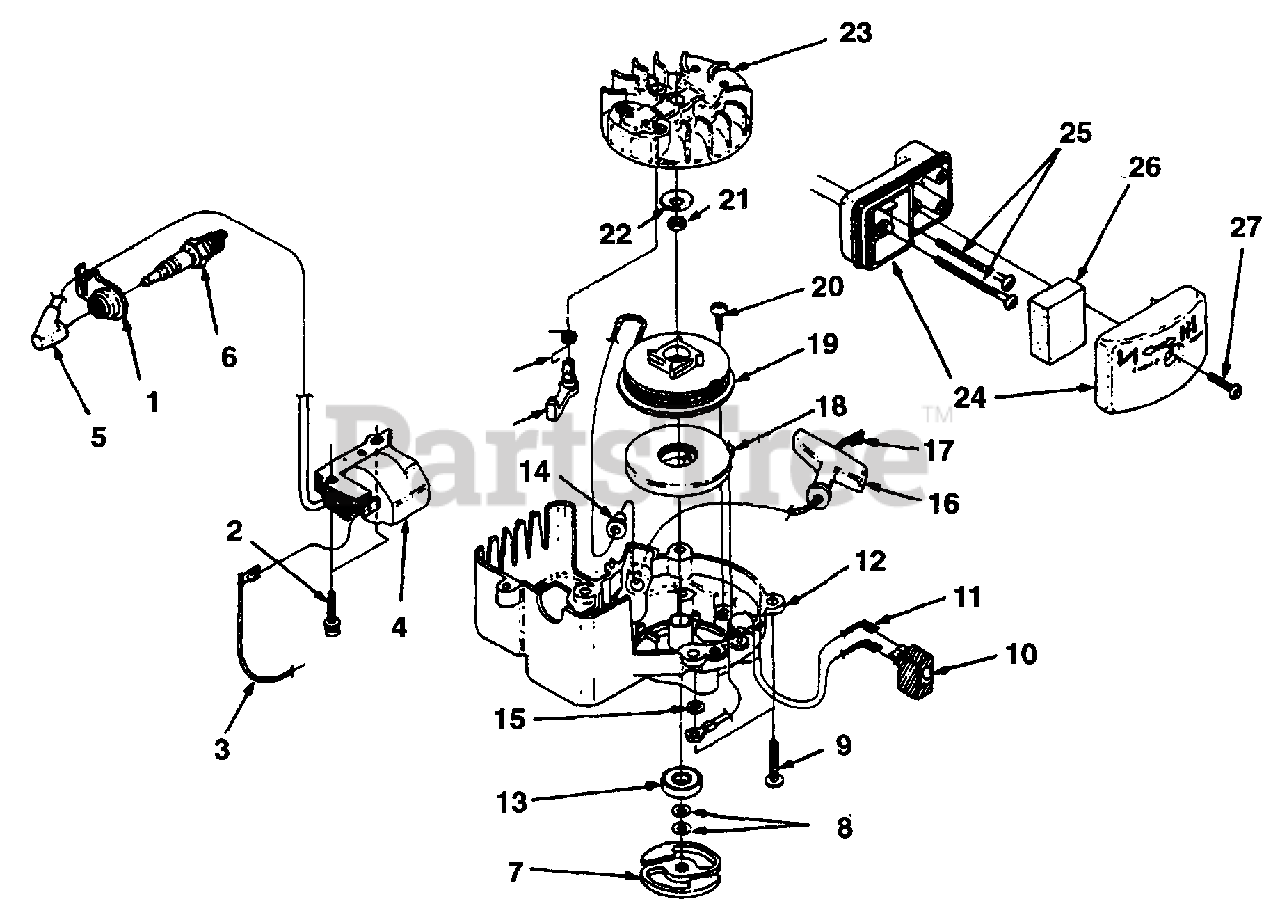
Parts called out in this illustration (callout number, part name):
1	SHIELD-Spark Plug
2	SCREW-Thread Form. (8-32 X 1")
3	LEAD-Electrical
4	MODULE-Ignition
5	SPARK PLUG BOOT KIT
6	SPARK PLUG (DJ-7Y)
6	SPARK PLUG (RDY-7Y) (HT17I, HT19I, HT21I)
7	CLUTCH "S"
8	WASHER-Belleville
9	SCREW-Taptite (10-24 X 3/4")
10	SWITCH
11	SWITCH (HT17I, HT19I, HT21I)
11	LEAD-Ground
12	HOUSING-Engine & Pulley
13	BEARING-Ball
14	BUSHING-Starter
15	WASHER-Flat (#10)
16	GRIP-Starter Rope
17	ROPE-Starter (42")
18	SPRING & CONTAINER
19	PULLEY-Starter
20	SCREW-Thread Form. (#10 X 1/2")
21	NUT-Hex (7/16-20)
22	WASHER-Conical
23	ROTOR
24	AIR FILTER HOUSING
25	SCREW-Machine (10-24 X 2 1/4")
26	FILTER-Air
27	SCREW-Thread Form. (#8 X .750)
